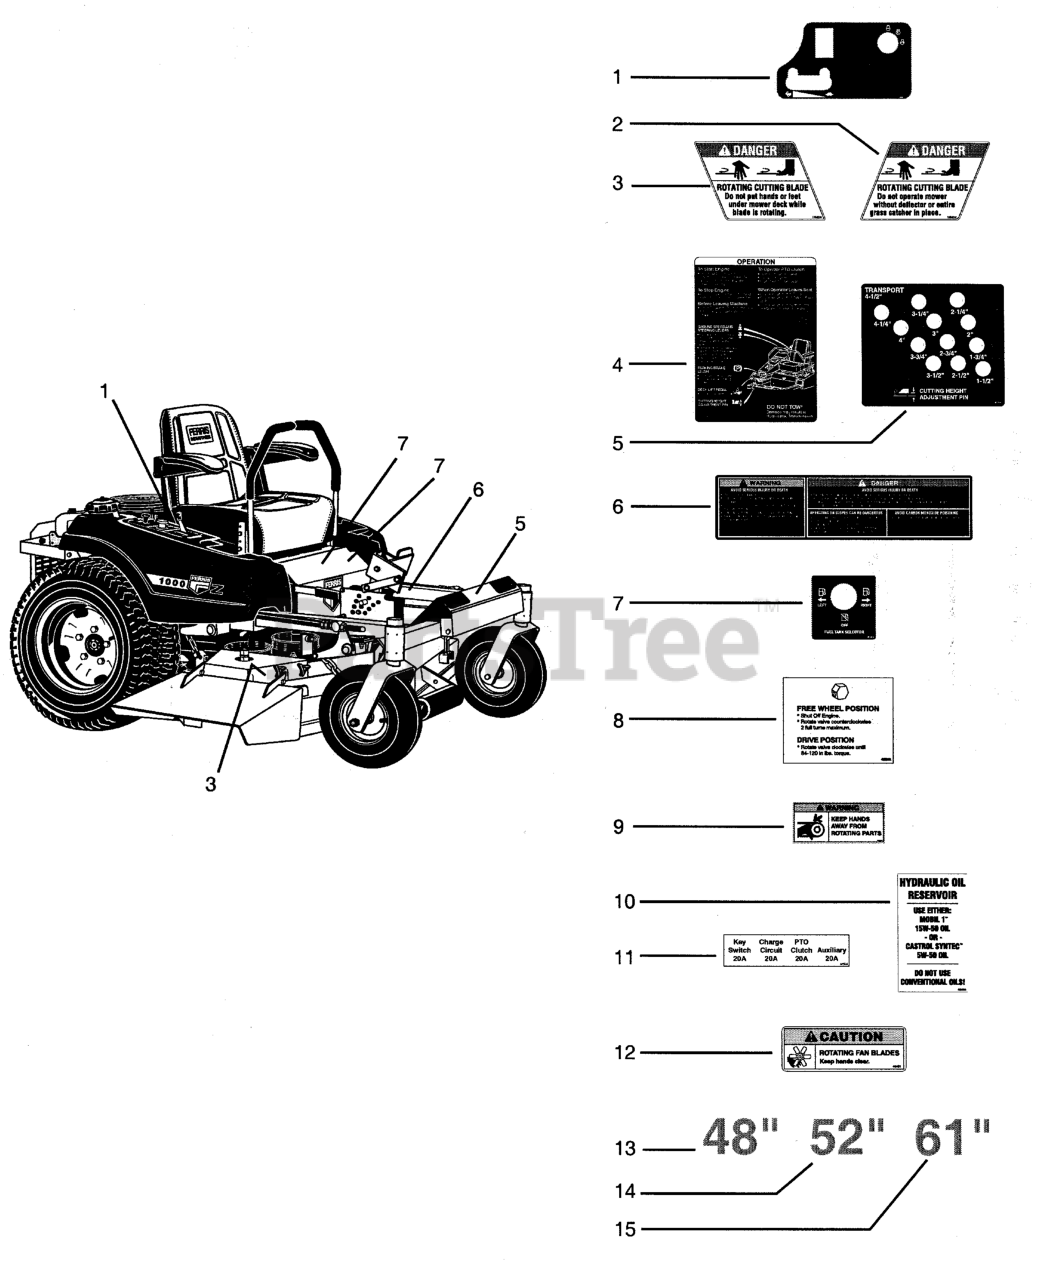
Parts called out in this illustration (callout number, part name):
1	DECAL, Control Panel
2	DECAL, Danger (Chute In Place)
3	DECAL, Danger (Hand Under Deck)
4	DECAL, Operation
5	DECAL, Lift Plate
6	DECAL, Safety/Instruction
7	DECAL, Fuel Selector
8	DECAL, Hydro Release Valve
9	DECAL, Warning
10	DECAL, Oil Reservoir
11	DECAL, Fuse Location
12	DECAL, Caution Fan
13	DECAL, 48
14	DECAL, 52
15	DECAL, 61"
